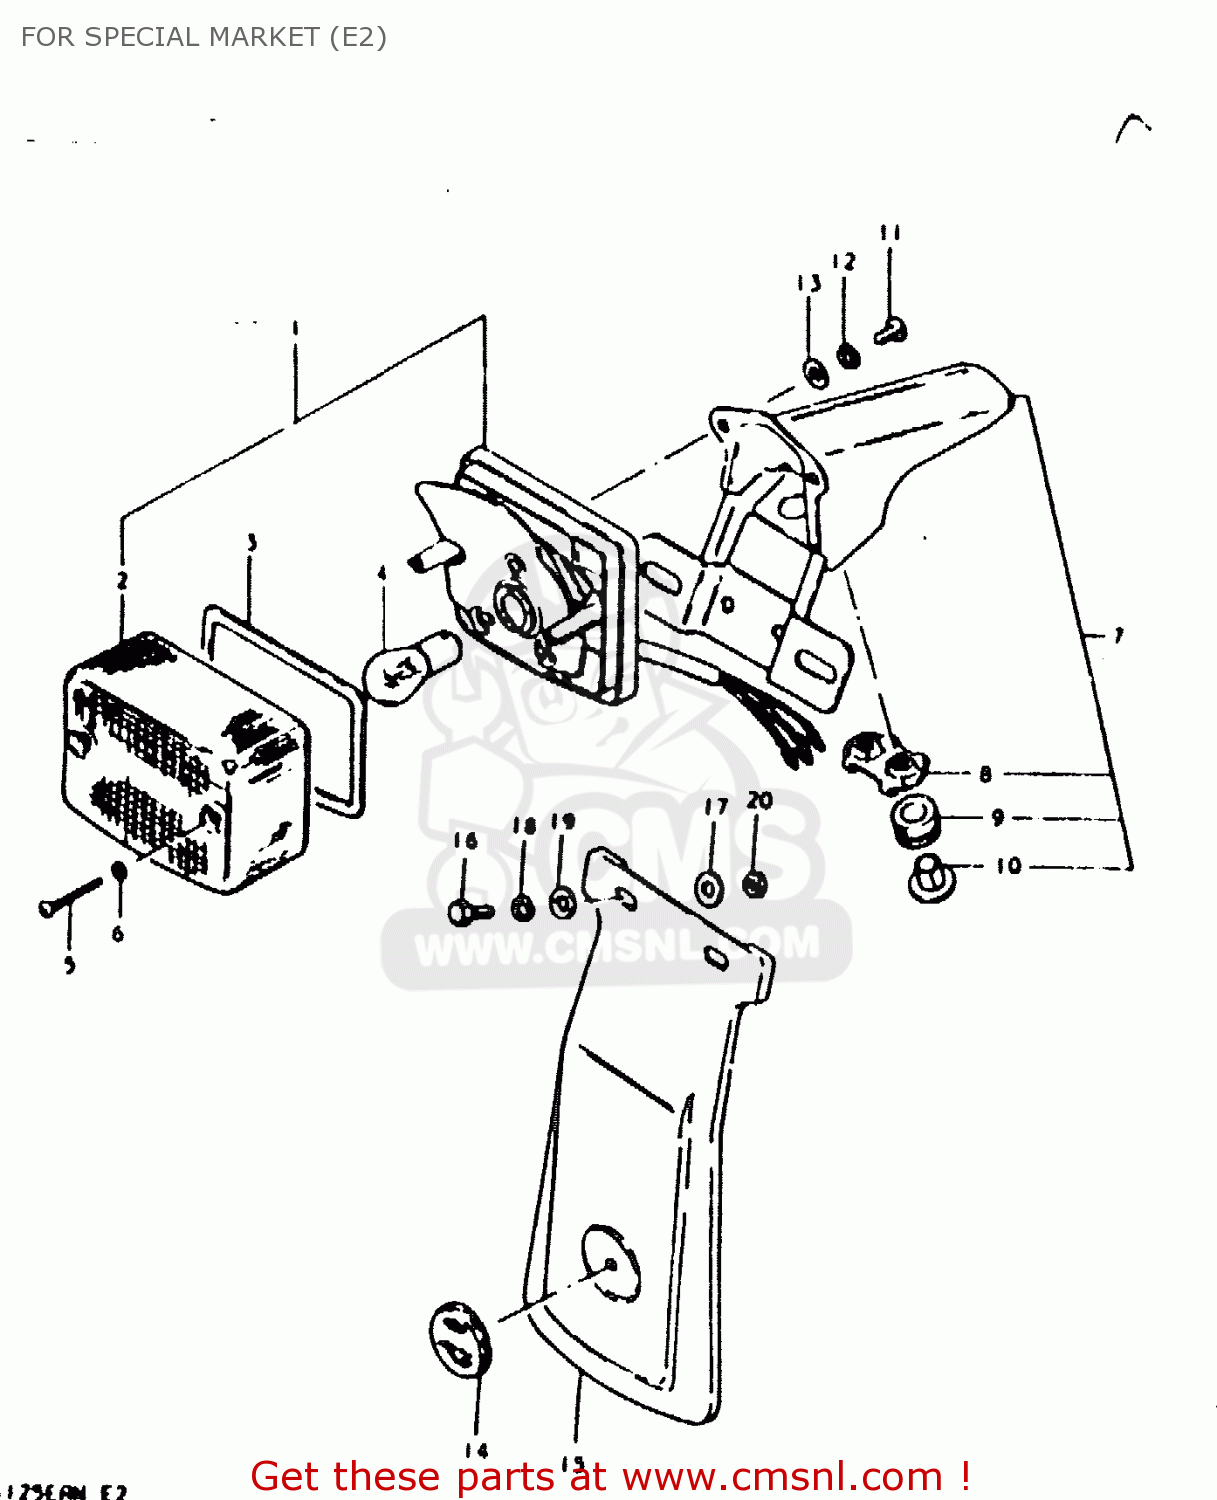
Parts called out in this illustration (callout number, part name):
1	LAMP UNIT, TAIL
2	LENS
3	GASKET (NAS)
4	BULB (6V,21/5W)
5	BOLT
6	GASKET (NAS)
7	BRACKET ASSY
8	PLATE
9	CUSHION
10	SPACER
11	SCREW
12	WASHER,LOCK
13	WASHER
14	REFLECTOR,REFLEX
15	MUD GUARD,REAR FENDER
16	BOLT, UPPER
17	WASHER
18	LOCK WASHER
19	WASHER
20	NUT
